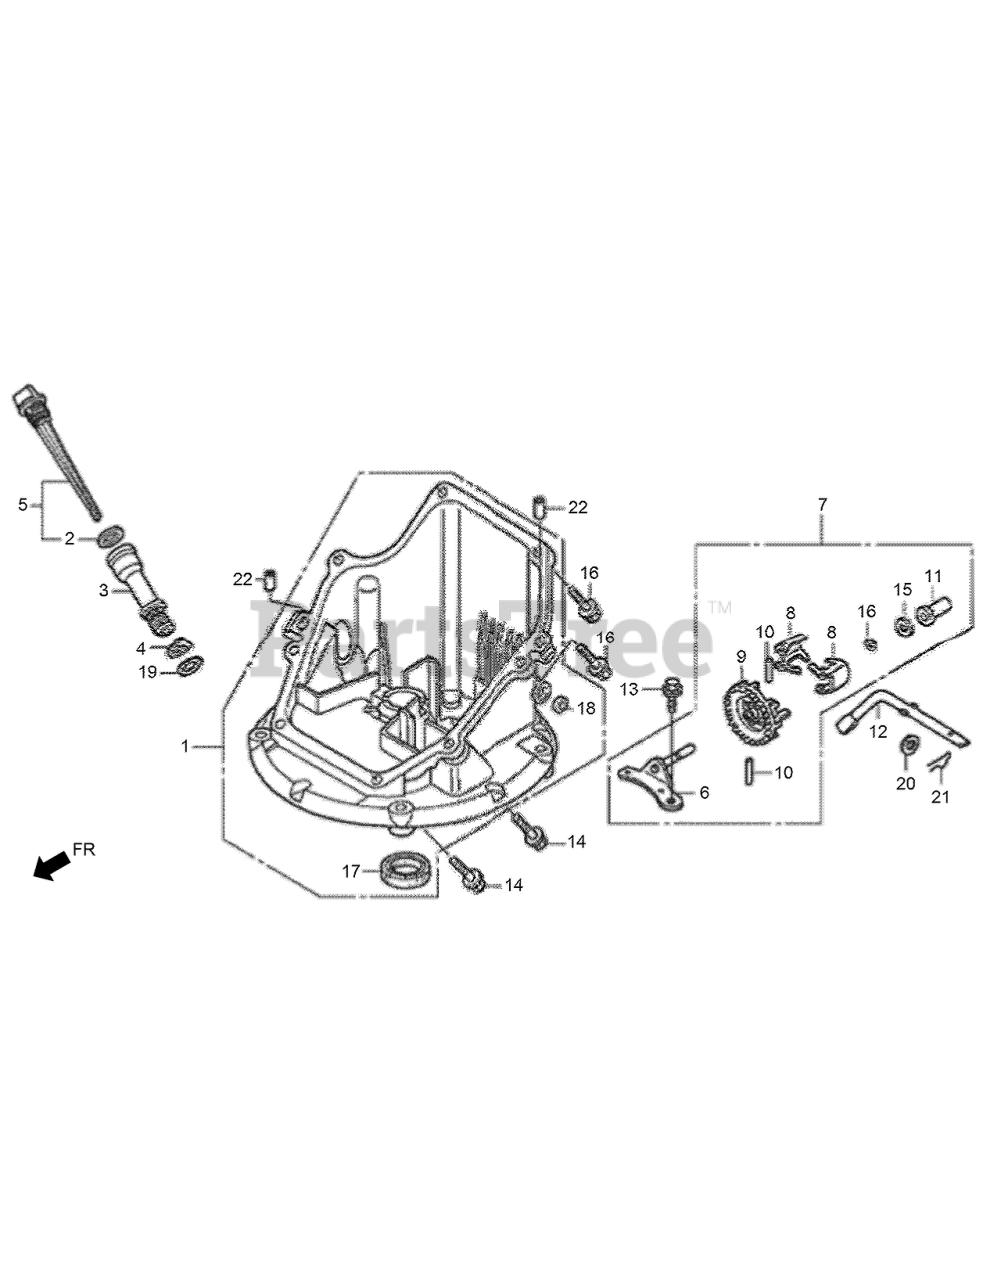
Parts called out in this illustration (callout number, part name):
1	PAN ASM-OIL
2	PACKING-OIL FILLER CAP
3	EXTENSION-OIL FILLER
4	WASHER-EXTENSION LOCK
5	GAUGE ASM-OIL LEVEL
6	GOVERNOR HOLDER SHAFT ASM
7	GOVERNOR ASM
8	WEIGHT-GOVERNOR
9	HOLDER-GOVERNOR WEIGHT
10	PIN-GOVERNOR WEIGHT
11	SLIDER-GOVERNOR
12	SHAFT-GOVERNOR ARM
13	BOLT-FLANGE-6X14
14	BOLT-FLANGE-6X25
15	WASHER-THRUST-6MM
16	CLIP-GOVERNOR HOLDER
17	OIL SEAL-28X41.25X6
18	OIL SEAL-6X11X4
19	O-RING-14.8X2.4
20	WASHER-PLAIN-6MM
21	PIN-LOCK-8MM
22	DOWEL PIN-8X20
